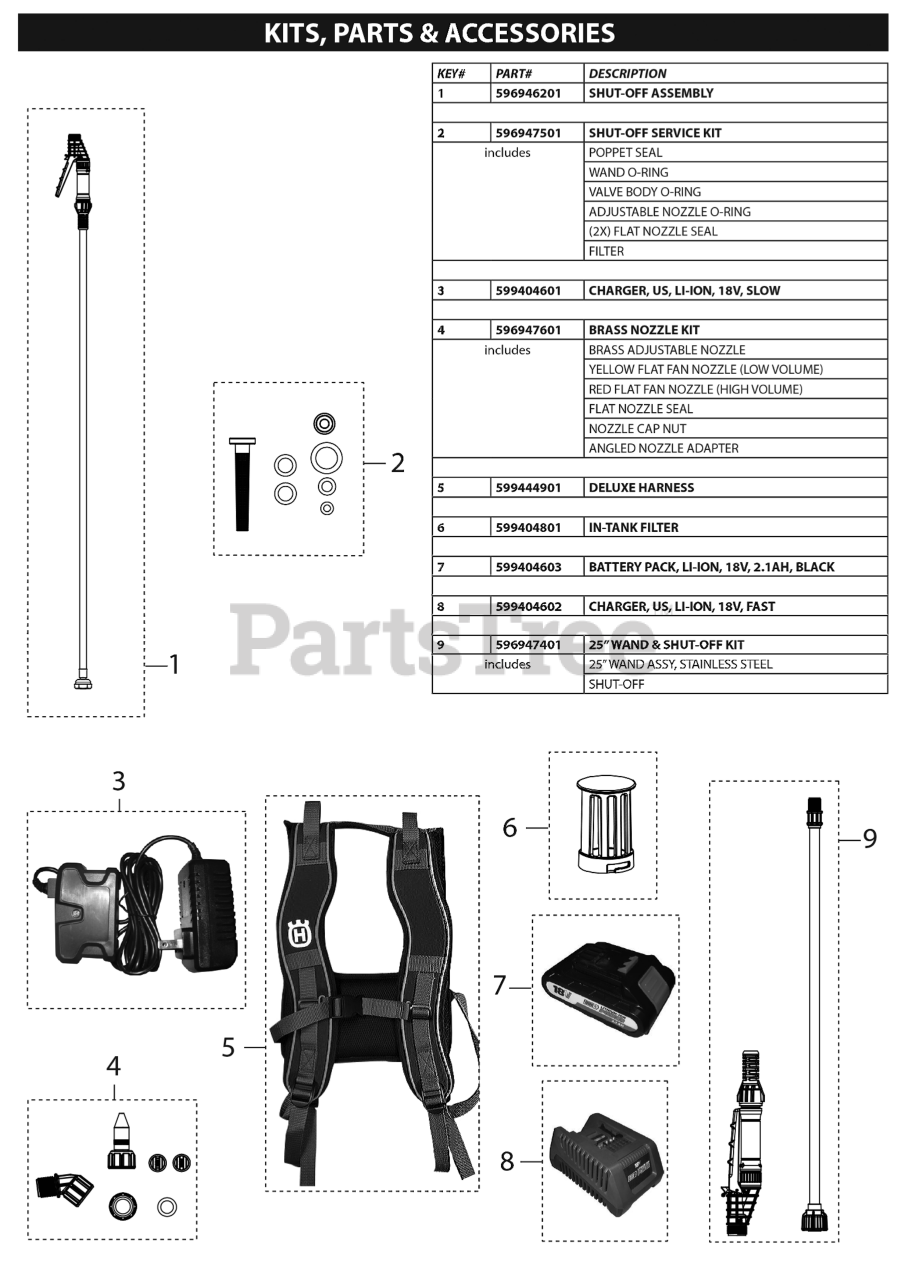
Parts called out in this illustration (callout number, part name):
1	4G SPRAYER SHUTOFF/HOSE ASSY
2	SPRAYER SHUTOFF SERVICE KIT
3	SPRAYERS
4	SPRAYER NOZZLE KIT
8	SPRAYERS
9	SPRAYER WAND/SHUTOFF KIT
